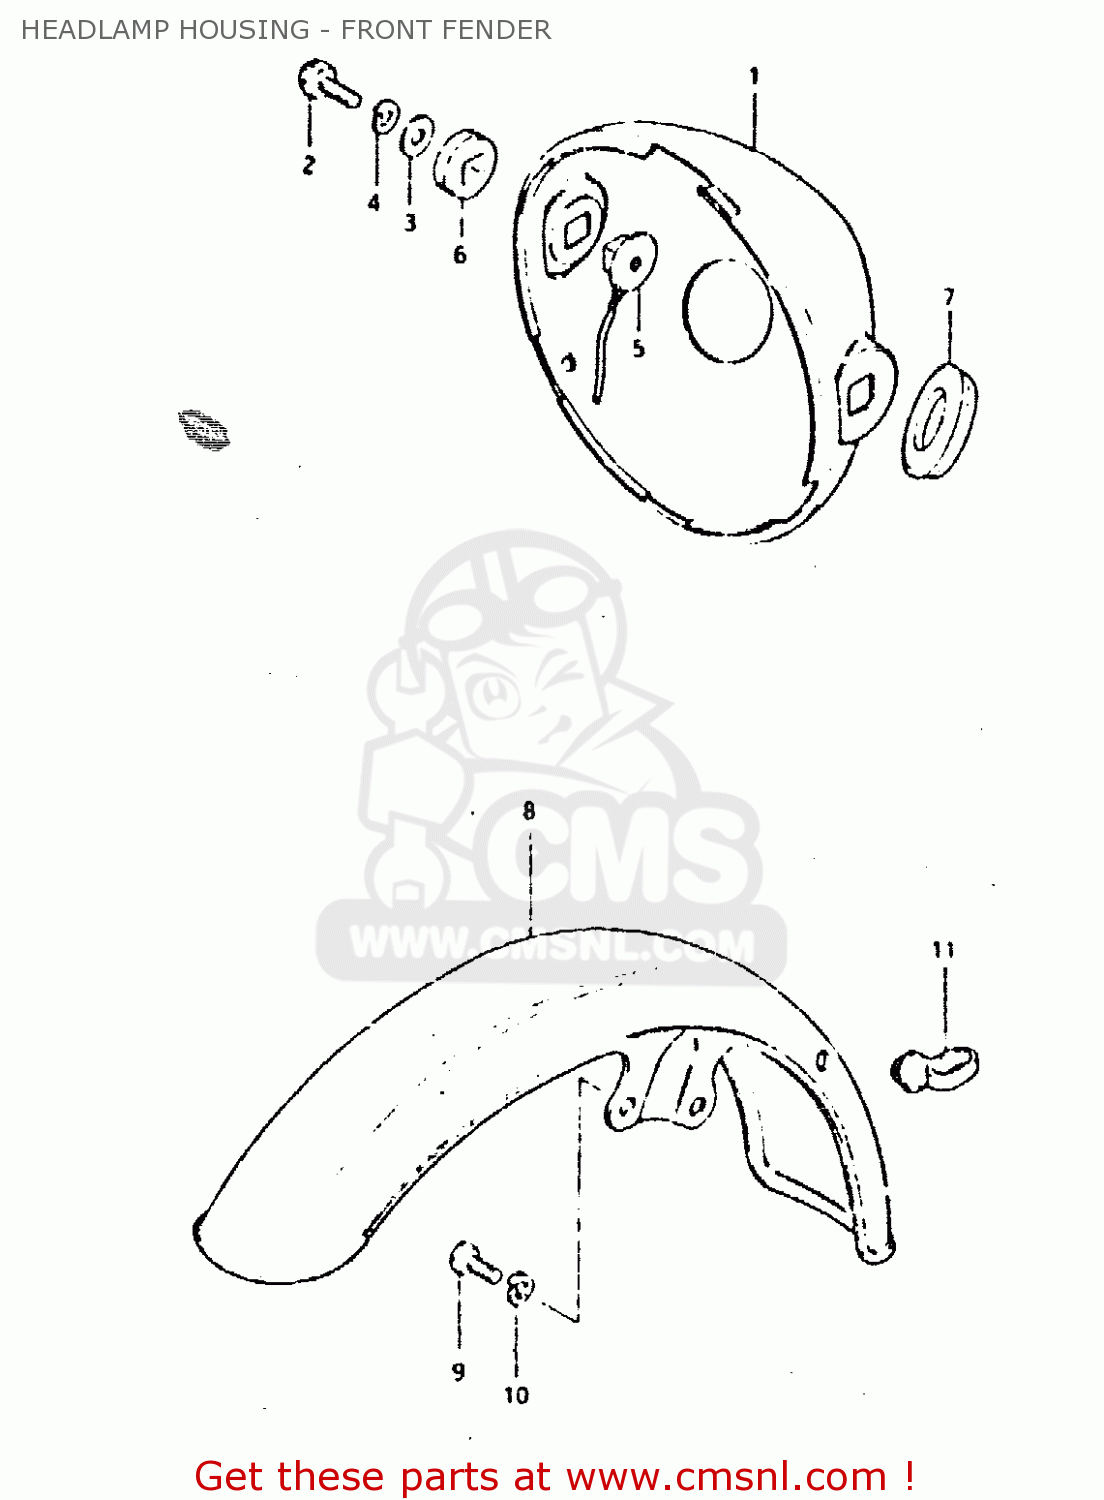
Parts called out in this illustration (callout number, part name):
1	HOUSING,HEADLAMP
2	BOLT
3	WASHER
4	LOCK WASHER
5	SPACER,HEADLAMP HOUSING
6	CUSHION,HEADLAMP HOUSING
7	GROMMET,HEADLAMP HOUSING
8	FENDER,FR
9	BOLT
10	LOCK WASHER
11	GUIDE,CABLE
